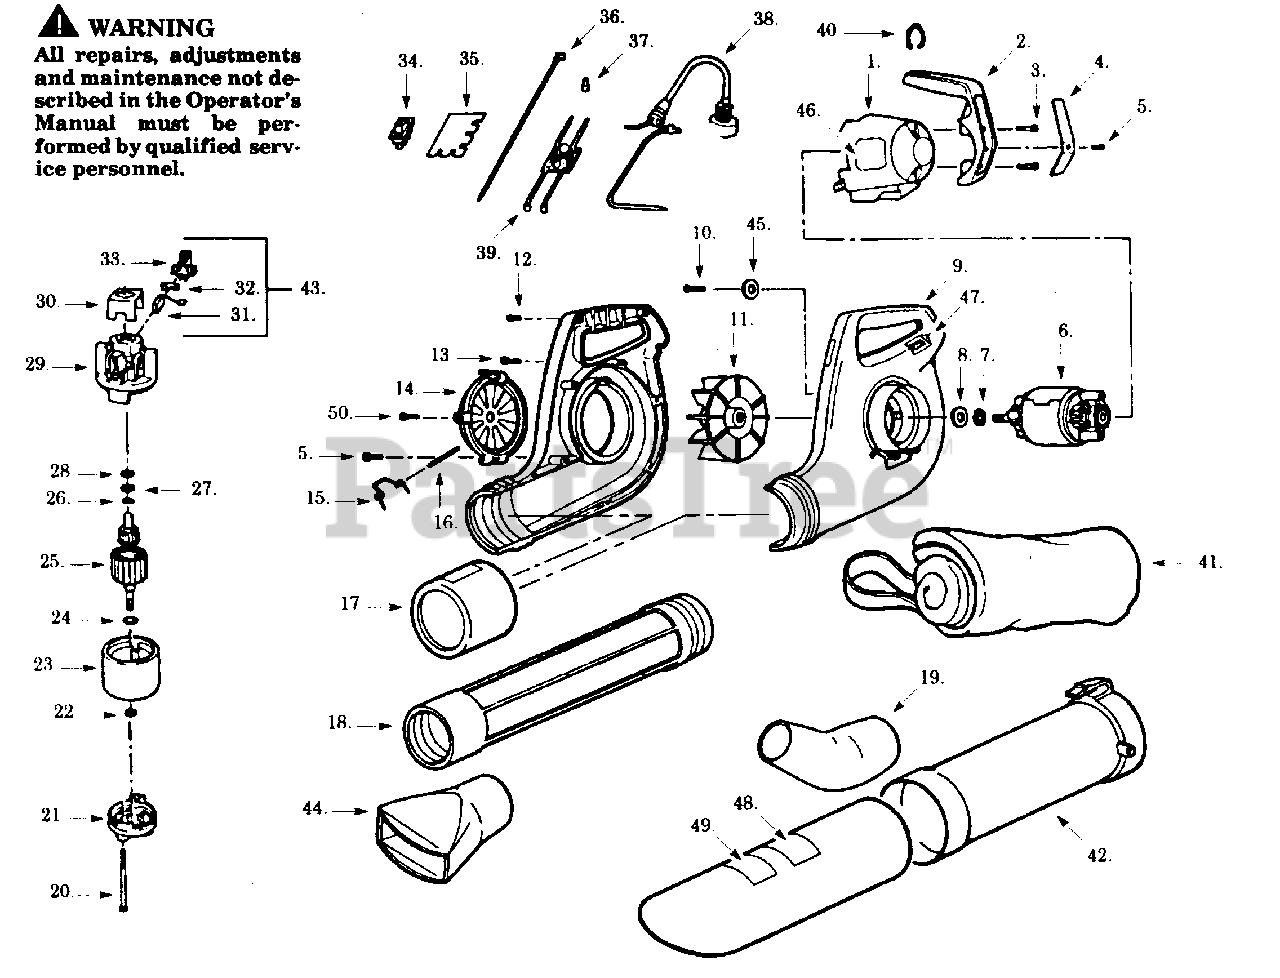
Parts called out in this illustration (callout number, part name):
1	Motor Cover
4	Plate Warning
7	Retaining Ring
9	L.H/R.H. Housing
11	Impeller Ass'y.
14	Inlet Cover
16	Hinge Pin
17	Ferrule Sleeve
18	Outlet Tube
19	Curved Nozzle
21	Endbell Ass'y. (Drive)
23	Field Ass'y.
24	Retaining Ring
25	Armature Ass'y.
26	Retaining Ring
29	Endbell Ass'y. (Brush)
30	Insulator
32	Brush Spring
33	Brush Holder
34	On-Off Switch Ass'y.
35	Mounting Board
36	Leadwire Ass'y.
37	Wire Nut
38	Power Cord Ass'y.
39	P.C. Board Ass'y.
41	Vacuum Bag
42	Vacuum Tube
43	Brush Kit (Incl. 31,32,33)
44	Diffuser Nozzle
46	Motor Cover Label (Not a serviceable part)
47	Switch Position Label
48	Name Plate Label
49	Warning Label-Tube
